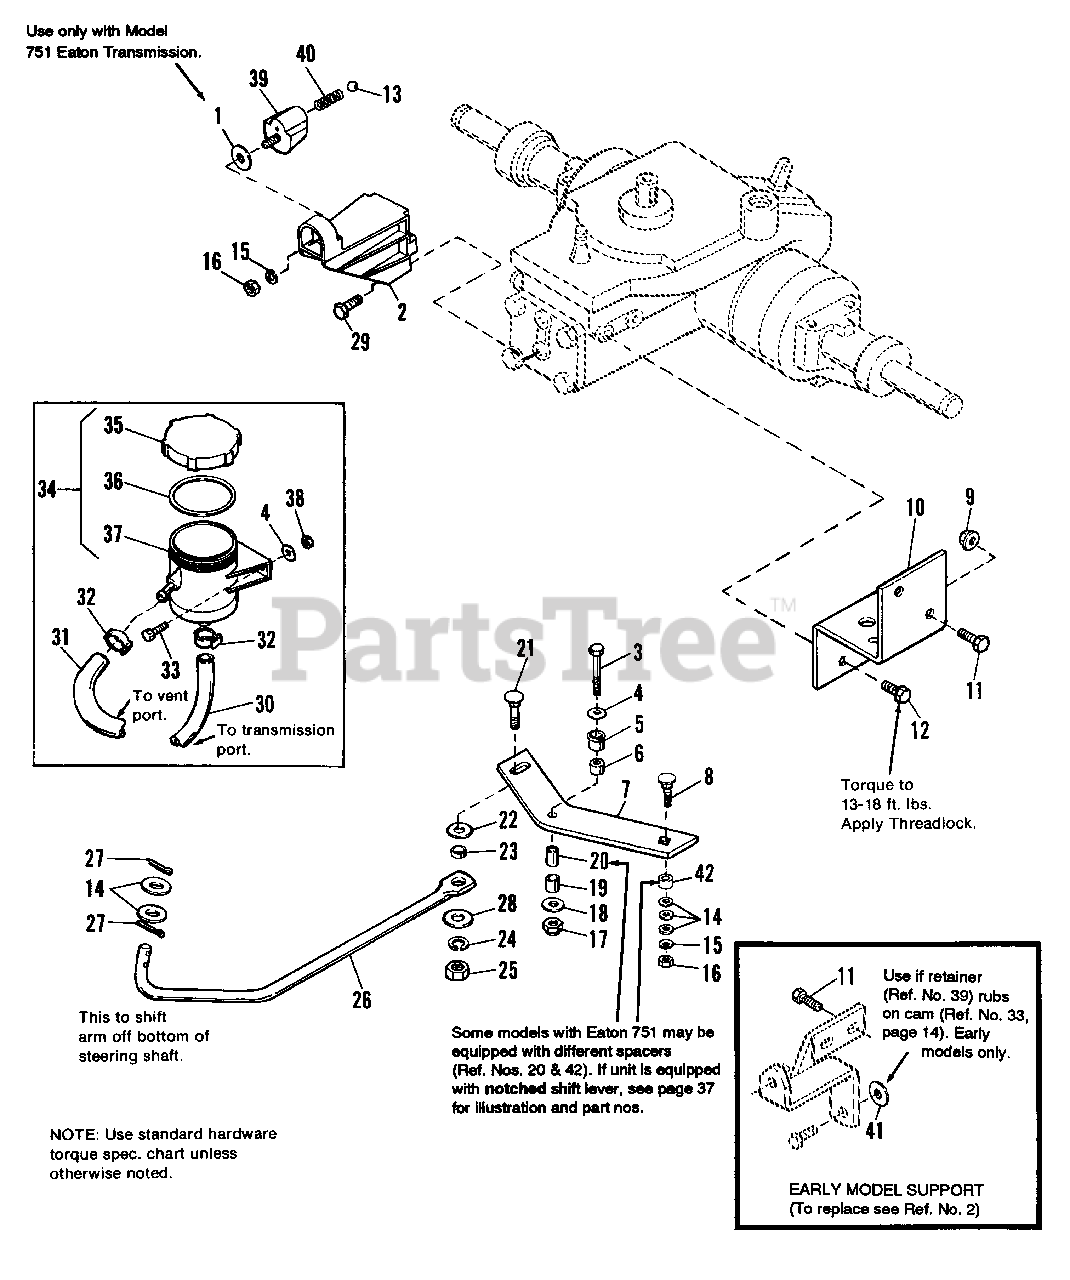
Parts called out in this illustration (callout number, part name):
2	SUPPORT, Detent
3	CAPSCREW, Hex Hd., 1/4-20 x 2
4	WASHER, 1/4
5	BUSHING, Plastic, 1/2 dia.
7	LEVER, Speed Control
8	CARRIAGE BOLT, 1/4-20 x 1-1/4
9	NUT, Flange Whizlock, 5/16-18
10	BRACKET, Transmission, Mounting
11	SCREW, Hex, Flange Whizlock, 5/16-18 x 3/4 (Qty. 4 on Early Models.)
12	SCREW, Hex, Flange Whizlock, 5/16-18 x 5/8
14	WASHER, 1/2
15	LOCKWASHER, 1/4
16	NUT, Hex Fu11, 1/4-20
17	NUT, Hex Lock, Esna, 1/4-20
18	WASHER
20	SPACER, Cam, Control
21	CARRIAGE BOLT, 5/16-18 x 1-1/4
22	WASHER, Plain
24	LOCKWASHER, 5/16
25	NUT, Hex, Full
26	ROD, Shift
27	COTTER PIN
28	WASHER, Plain
29	SCREW, Taptite, 5/16-18 x 3/4
30	HOSE, Hydro to Reservoir, 66" Hose (12.5 HP Only)
30	HOSE, Hydro to Reservoir, 58" Hose (16 HP Only)
31	HOSE, Reservoir to Hydro, Vent, 52" Hose (12.5 HP Only)
31	HOSE, Reservoir to Hydro, Vent, 46" Hose (16 HP Only)
32	CLAMP, Hose
33	CAPSCREW, 1/4-20 x 5/8
34	RESERVOIR ASSY. (Incl. Ref. Nos. 35, 36, 37)
38	NUT, Hex Lock, Nylon, 1/4-20
39	RETAINER, Ball
41	WASHER, Special, Nylon (Used on early models)
